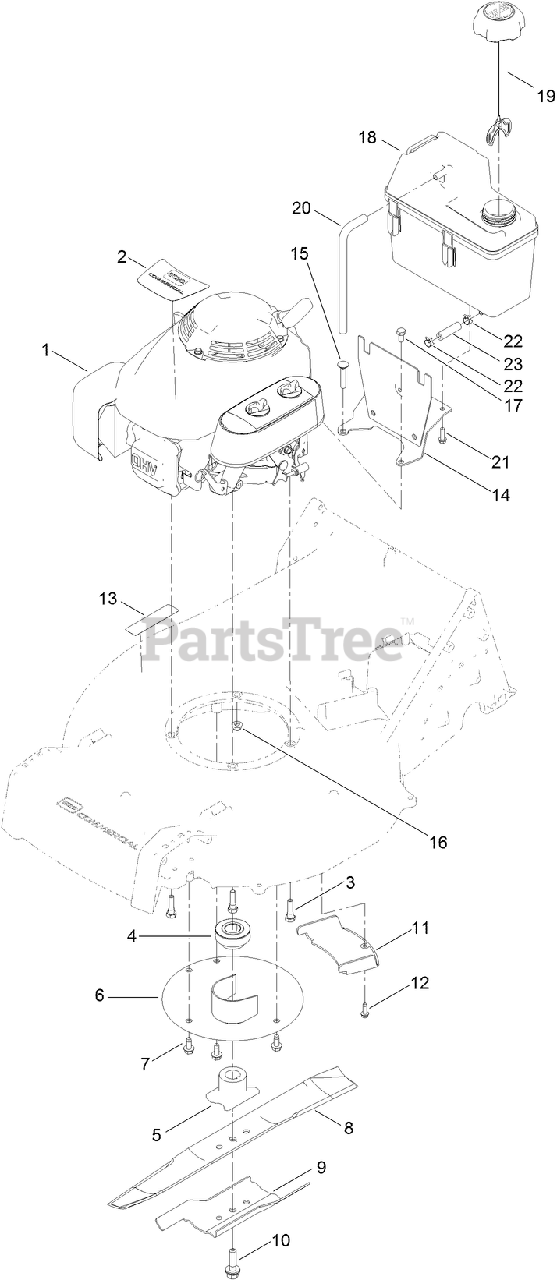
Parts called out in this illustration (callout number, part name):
2	DECAL-ENGINE, HONDA
3	SCREW-HHSH
4	PULLEY-DRIVER
5	DRIVER-BLADE
6	PROTECTOR-CRANKSHAFT
7	SCREW-HWHTF
8	BLADE-21IN, RECYCLING
9	ACCELERATOR-BLADE
10	BOLT-BLADE
11	COVER-BELT
12	SCREW-HWHTF
13	DECAL-ARRESTOR, SPARK
14	MOUNT-TANK
15	BOLT-CAR
16	NUT-HF, NI
17	SCREW-HH
18	TANK-FUEL
19	CAP-FUEL
20	HOSE-VENT, CANISTER
21	SCREW-HWH
22	CLAMP-HOSE
23	HOSE-FUEL
